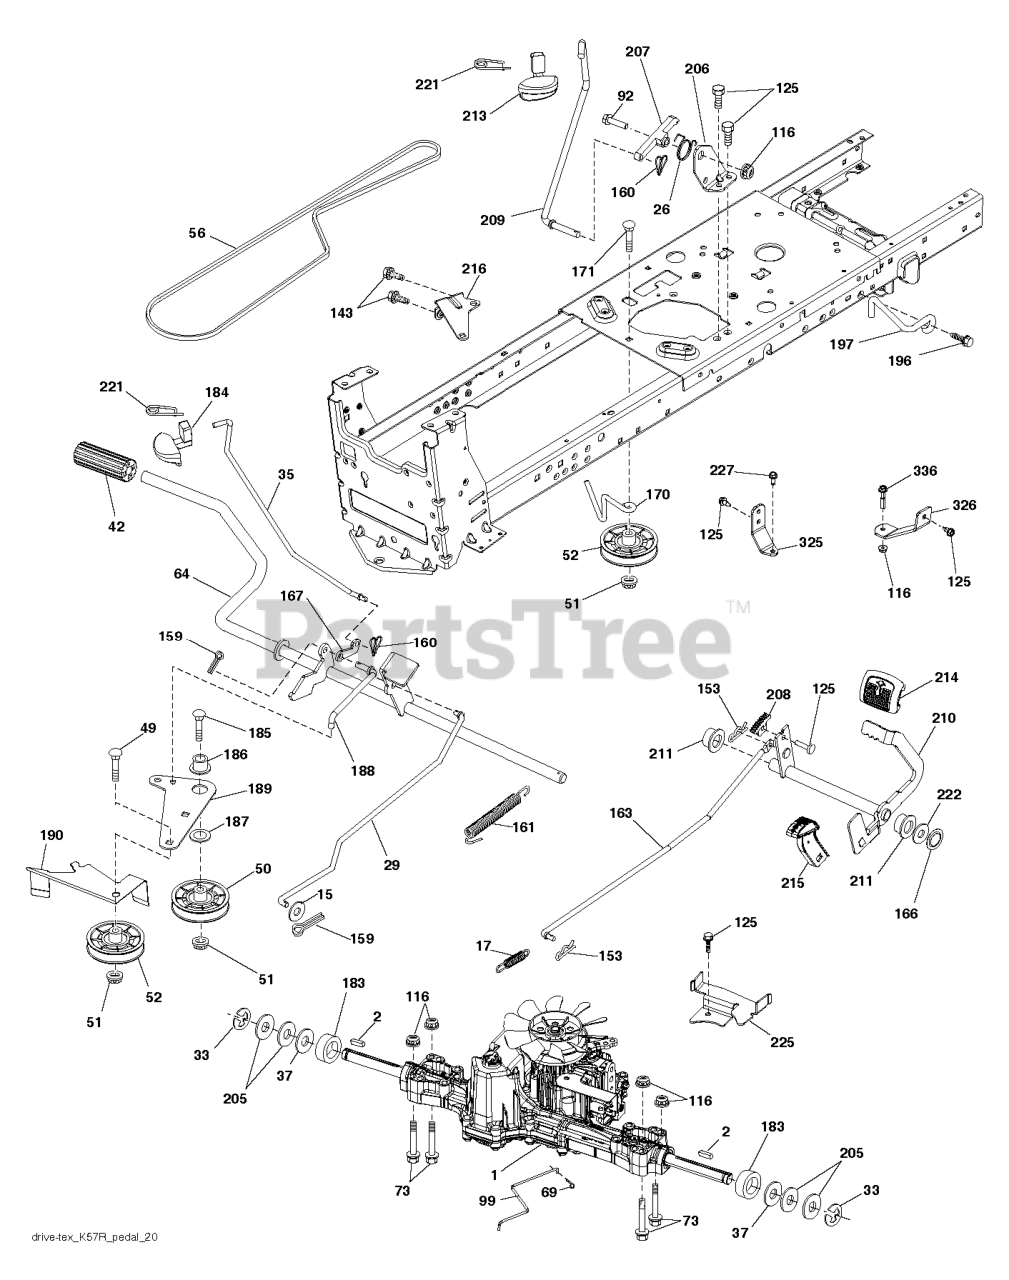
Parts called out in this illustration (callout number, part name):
2	SQUARE KEY
15	WASHER
17	SPRING.BRAKE.K46.GREEN
26	SPRING.RETURN.CRUISE
29	ROD.BRAKE.K46
35	ROD .BRAKE. PARKING. GT. HUSQ.
37	WASHER.HARDENED
42	PEDAL COVER T
50	IDLER.FLAT.910.OFFSET
51	NUT LOCK FLG 3/8-16 UNC
52	IDLER.V-GROOVE.910.OFFSET
56	V-BELT.MOWER.92.40.42/K46
64	SHAFT.ASM.PEDAL.BRK.CNTR
73	BOLT
92	BOLT
99	ROD.SPRING.BYPASS.K46.LT.Z
116	NUT LOCK HEX FLANGE 5/16-18
125	SCREW
143	SCREW LT
153	RETAINER M
159	COTTER PIN
160	RETAINER CLIP
161	SPRING, RETURN LT
163	ROD.CONTROL.K57R.K46
166	NUT.PUSH.625
167	LATCH.BRAKE.SPRING
170	KEEPER.V-IDLER.CENTER.
171	BOLT
183	SPACER AXLE
184	HANDLE.PARKING.BRAKE.H (BLK)
186	SPACER.RETAINER
187	WASHER 12/32X2X10GA
188	RP.LINK.CLUTCH.GROUND.DRIVE
189	BELLCRANK.GROUND.DRIVE.TEX.
190	KEEPER.BELLCRANK.DRIVE
196	SCREW 3/8-16X1
197	CLUTCH.ANTIROTATION.WIREFORM.
206	BRACKET.MOUNT.CRUISE.LATCH
207	LATCH.CONTROL.CRUISE.TEX
208	GEAR.SECTOR.CONTROL.CR
209	ROD.CONTROL.CRUISE.GT.
210	ROCKER.ASM.PEDAL.CONTR
211	BEARING.NYLON
213	KNOB.CONTROL.CRUSIE.HU
214	PEDAL.FORWARD.PAD.TEX
215	PEDAL.COVER.REVERSE.CRD.X498GY
216	BRACKET.PULLEY.IDLER.W/TEX
221	RETAINER.SPRING.CLIP.H
222	WASHER 21/32 X 1-1/4 X 10 GA.
225	KEEPER.BELT.TRANSAXLE.K46
227	SCREW.THDROL.5/16-18X3/4.TTY
325	BRACKET.TRQ.STP.46.20".TIRE.LH
326	BRCKT.PNT.TRQ.STP.46.20TIRE.RH
336	BOLT.5/16-18X1-3/4.FLANGED.HEX
